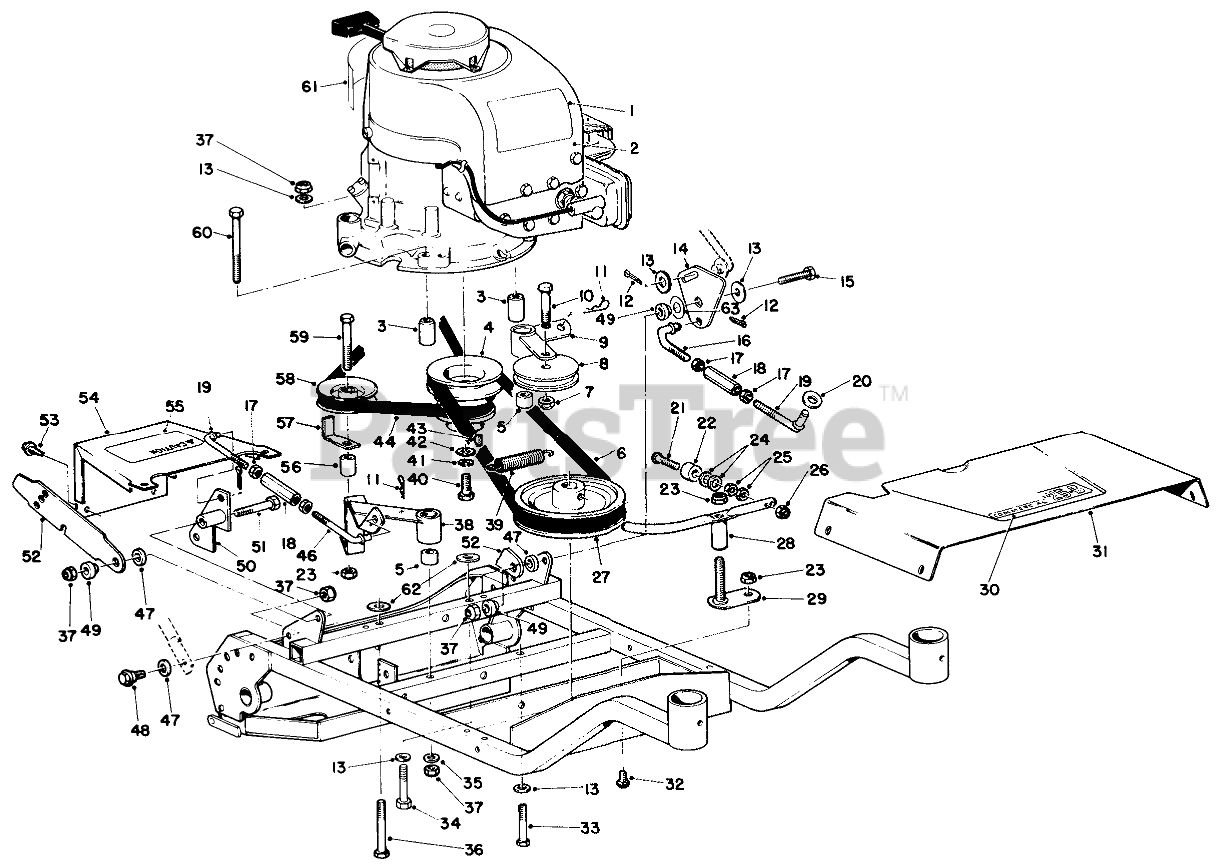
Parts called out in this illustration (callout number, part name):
1	Decal
2	Engine
3	ENGINE PIVOT SPACER
4	ENGINE PULLEY RO
5	BUSHING
7	Nut
8	PULLEY B
9	Arm and Bushing (Incl. Ref. #5)
10	Screw
11	PIN-COTTER
12	PIN-COTTER
13	WASHER-PLAIN
14	CUTTR BELLCRANK WA R
15	5/16-18 X 1-3/4 SCREW
16	CUTTER LINK
17	NUT-KEPS
18	CONTROL ROD SLEEVE
19	LINK CONTROL ROD
20	WASHER
21	10-24X1-1/2 RND HD MS
22	BUMPER
23	NUT-HEX
24	WASHER-FLAT
25	NUT-HEX
26	NUT-LOCK, NI
27	Pulley
28	Brake Arm
29	Base Pivot
30	DECAL
31	FRONT SHROUD R
32	SCREW-CARR
33	SCREW-HH
34	SCREW-HH
35	WASHER-LOCK/SP
36	SCREW-HH
37	Nut
38	Arm and Bushing (Incl. Ref #5)
39	EXTENSION SPRING
40	Screw
41	WASHER-LOCK
42	WASHER-FLAT
43	KEY-WOODRUFF
44	V-BELT
46	Control Rod
47	SPACER
48	SCREW-SHOULDER
49	PIVOT
50	TRACT BELLCRANK WA R
51	SCREW-HH
52	HANDLE LATCH
53	10-16 X 3/8 THDG SCREW
54	Rear Shroud
55	DECAL SAF INST
56	SPACER
58	IDLER PULLEY R
59	SCREW-HH
60	SCREW-HH
61	Decal
62	WASHER
63	WASHER
